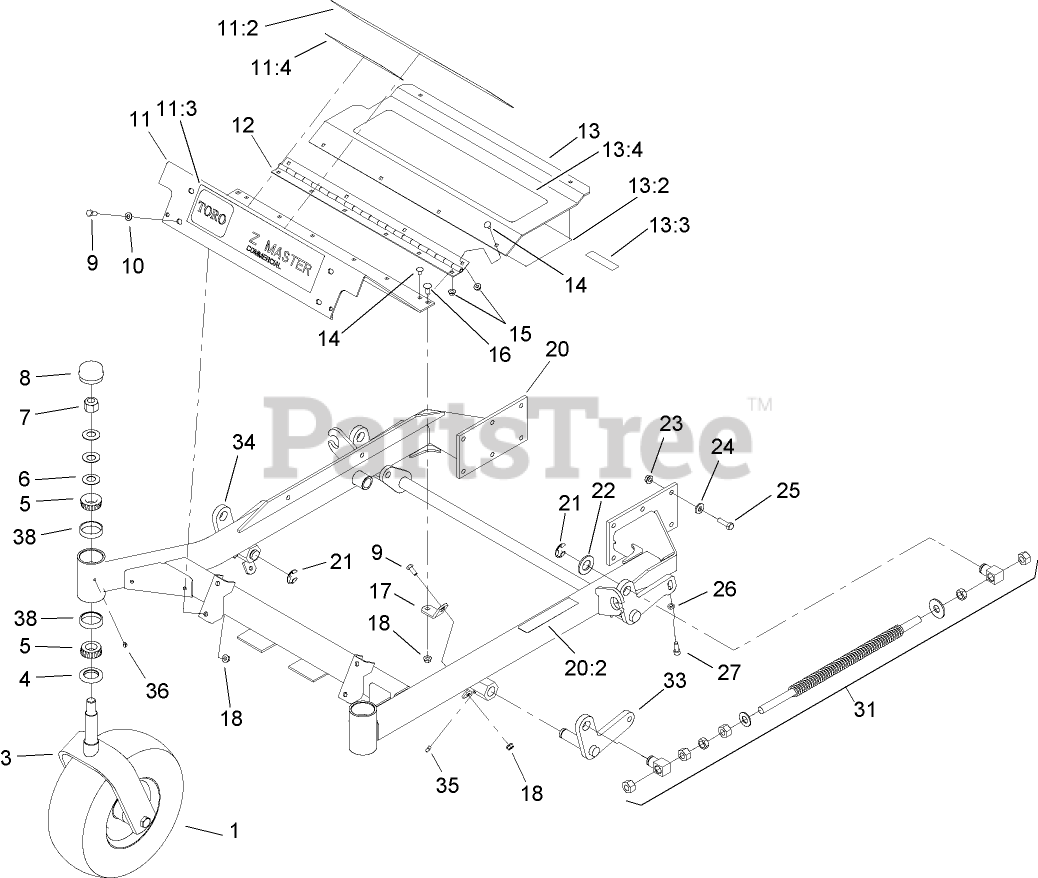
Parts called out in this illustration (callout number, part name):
1	CASTER WHEEL ASM
3	CASTER
4	SEAL-GREASE
5	BEARING-CONE, TAPERED
6	WASHER-BELLVILLE
7	NUT-LOCK, NI
8	CAP-GREASE
9	SCREW-HH
10	WASHER-PLAIN
11	FLOORPAN ASM
11:2	PAD-ANTISKID
11:4	DECAL-DANGER, SLOPE
12	HINGE-FLOORPAN
13	FOOTREST ASM
13:2	DECAL-SERVICE, CE
13:3	DECAL-WARNING
13:4	PAD-ANTISKID
14	SCREW-CARR
15	NUT-HF
16	BOLT-CARR
17	BRACKET-FLOORPAN
18	NUT-HF
20	FRONT FRAME ASM
20:2	DECAL-WARNING
21	RING-RETAINING, EXT
22	WASHER-FLAT
23	NUT-HHF, WHIZ
24	WASHER-BELLEVILLE
25	SCREW-HH
26	NUT-JAM
27	SCREW-HSH
31	Front Spring ASM
33	LH FRONT DECK LIFT ASM
34	RH FRONT DECK LIFT ASM
35	FITTING-GREASE
38	BEARING-CUP, TAPERED
